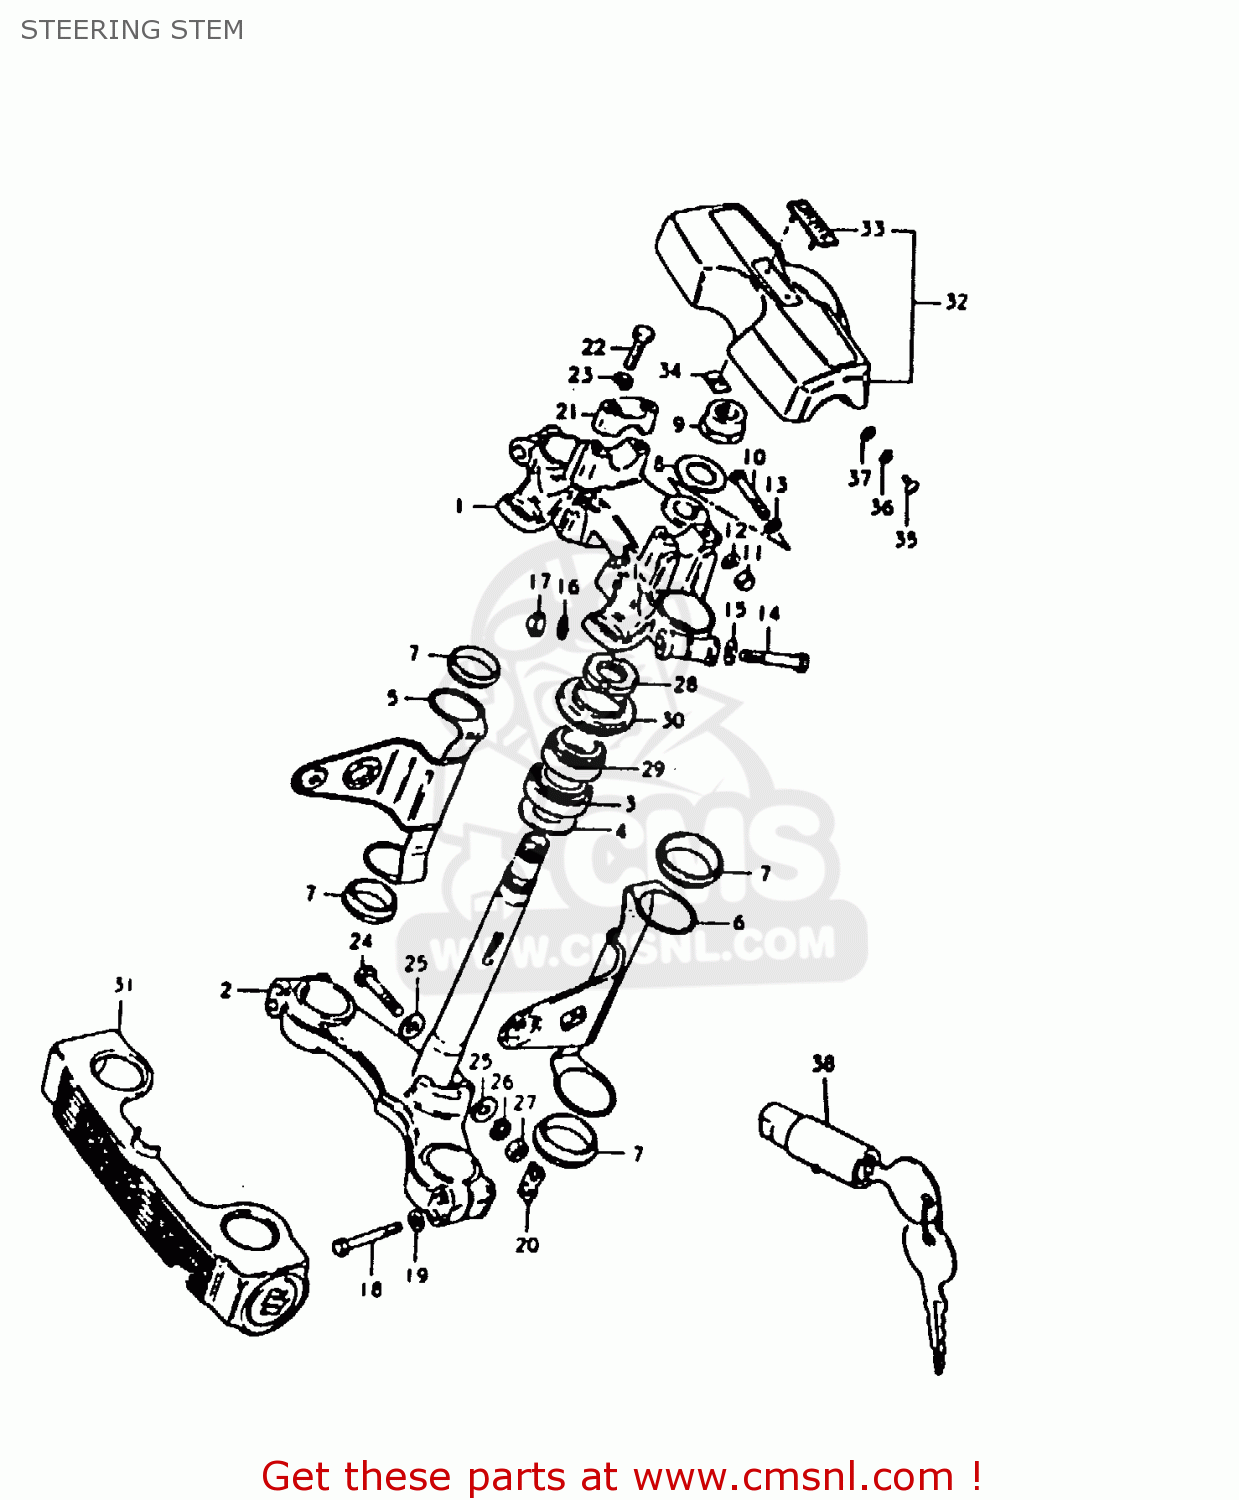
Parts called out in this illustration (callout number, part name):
1	HEAD,STEERING STEM
2	STEM,STEERING
3	BEARING
4	WASHER,THRUST
5	BRACKET,HEADLAMP,RIGHT
6	BRACKET,HEADLAMP,LEFT
7	CUSHION,HEADLAMP BRACKET
8	WASHER
9	NUT,FR FORK UPR BRACKET
10	BOLT 8X50
11	NUT
12	LOCK WASHER
13	WASHER
14	BOLT 10X55
15	WASHER
16	LOCK WASHER
17	NUT, LOWER LH
18	BOLT 8X55
19	WASHER
20	NUT,FR FORK INNER TUBE
21	HOLDER,HANDLE(BLACK)
22	BOLT
23	LOCK WASHER
24	BOLT
25	WASHER
26	LOCK WASHER
27	NUT
28	NUT,STEERING STEM(25X44X10)
29	TAPER,ROLLER BEARING
30	DUST SEAL,STEERING,UPPER
31	COVER, FRONT FORK
32	PAD,HANDLEBAR
33	EMBLEM,HANDLE COVER PAD
34	NUT
35	SCREW
36	LOCK WASHER
37	WASHER
38	LOCK ASSEMBLY,STEERING (NEI
